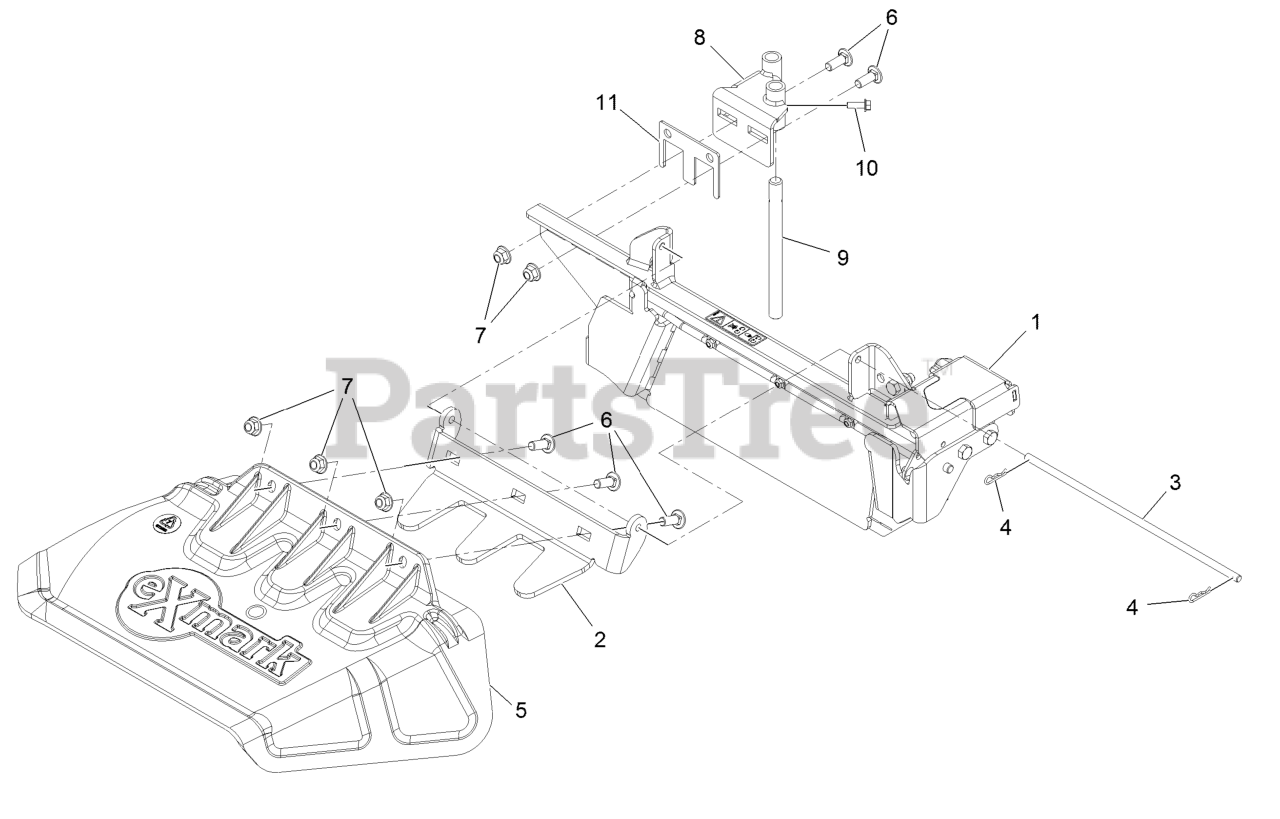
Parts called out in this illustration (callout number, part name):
1	ASM, Ocd Gate
2	Mount, Discharge Chute
3	Pin,Chute
4	Hairpin-Cotter
5	Chute, Discharge
6	Bolt-Carriage 3/8-16 X 1
7	Nut-Nyloc 3/8-16 Flg
8	Weldment, Ocd Mount
9	Pin-Mount, Ocd
10	Screw-Hex Flange 1/4-20 X 3/4
11	Shim-Ocdwb
